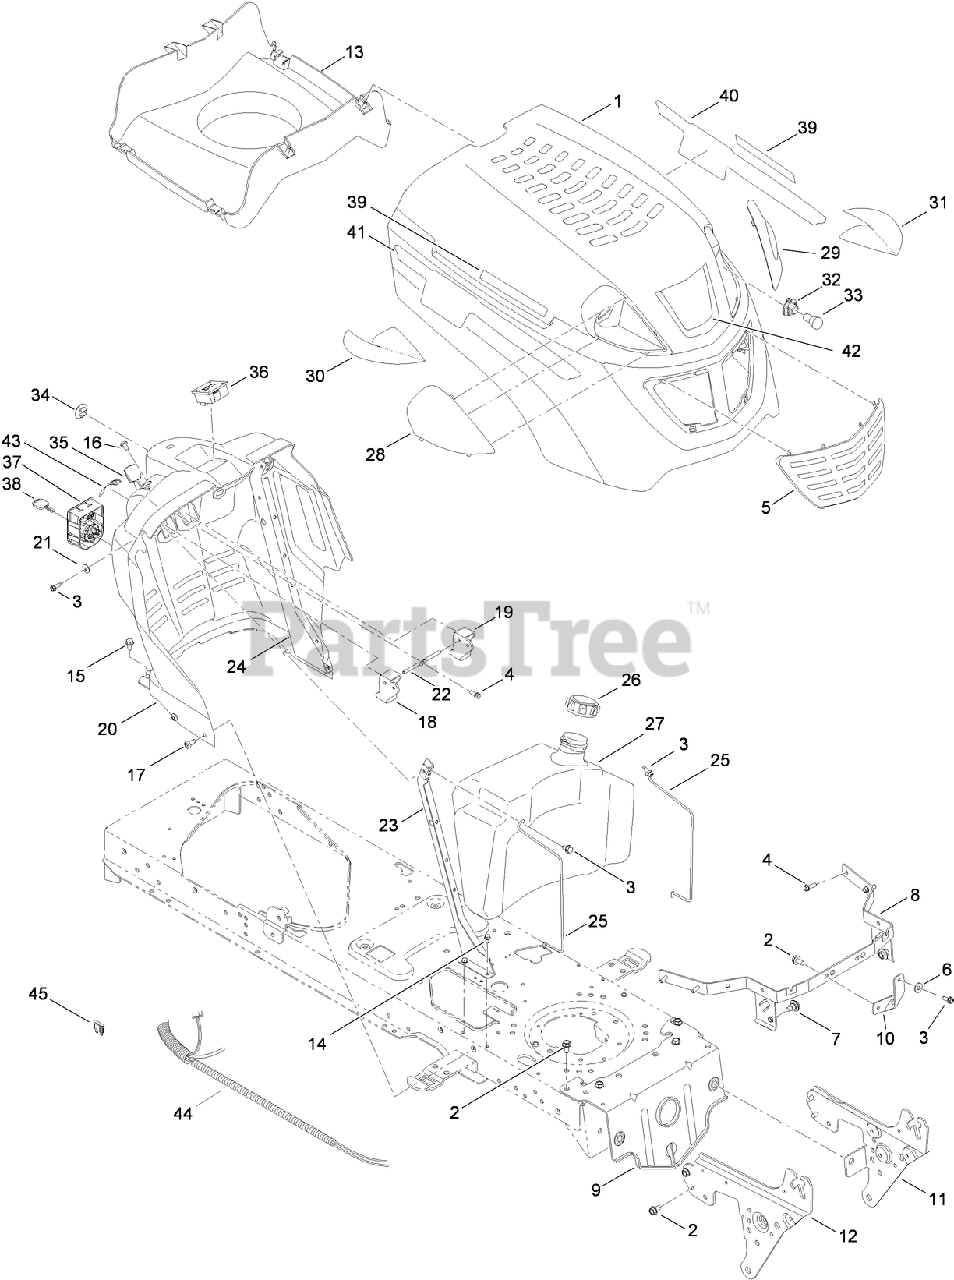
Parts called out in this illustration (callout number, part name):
2	SCREW-TAP
3	SCREW-TAP
4	SCREW-TAP
6	WASHER-FLAT
7	BOLT-SHOULDER, TAP
8	BRACKET-PIVOT
9	BRACKET-PIVOT
10	BRACKET-SUPPORT, HOOD
11	BRACKET-SUPPORT, PIVOT (LH)
12	BRACKET-SUPPORT, PIVOT (RH)
13	PLENIUM-HOOD
14	SCREW-HWHTF
15	SCREW-TAP
16	SCREW-TAP
17	SCREW-TAP
18	LEVER-CRUISE
19	LEVER-BRAKE
20	DASH-MANUAL, PTO
21	WASHER-SPRING
22	ROD-LEVER, BENT
23	SUPPORT-DASH, PLATE (RH)
24	SUPPORT-DASH, PLATE (LH)
25	ROD-SUPPORT
26	CAP-FUEL
27	TANK-FUEL, 3 GAL
28	LENS-RH
29	LENS-LH
30	REFLECTOR-RH
31	REFLECTOR-LH
32	SOCKET-HEADLIGHT
33	LAMP-12V, MINIATURE
34	PLUG-CHOKE
35	CABLE-THROTTLE
36	METER-HOUR
37	MODULE-SWITCH, IGNITION
38	KEY-IGNITION
40	DECAL-HOOD, LEFT SIDE
41	DECAL-HOOD, RIGHT SIDE
42	DECAL-HOOD
43	DECAL-THROTTLE
44	HARNESS-WIRING
45	FUSE-20 AMP
